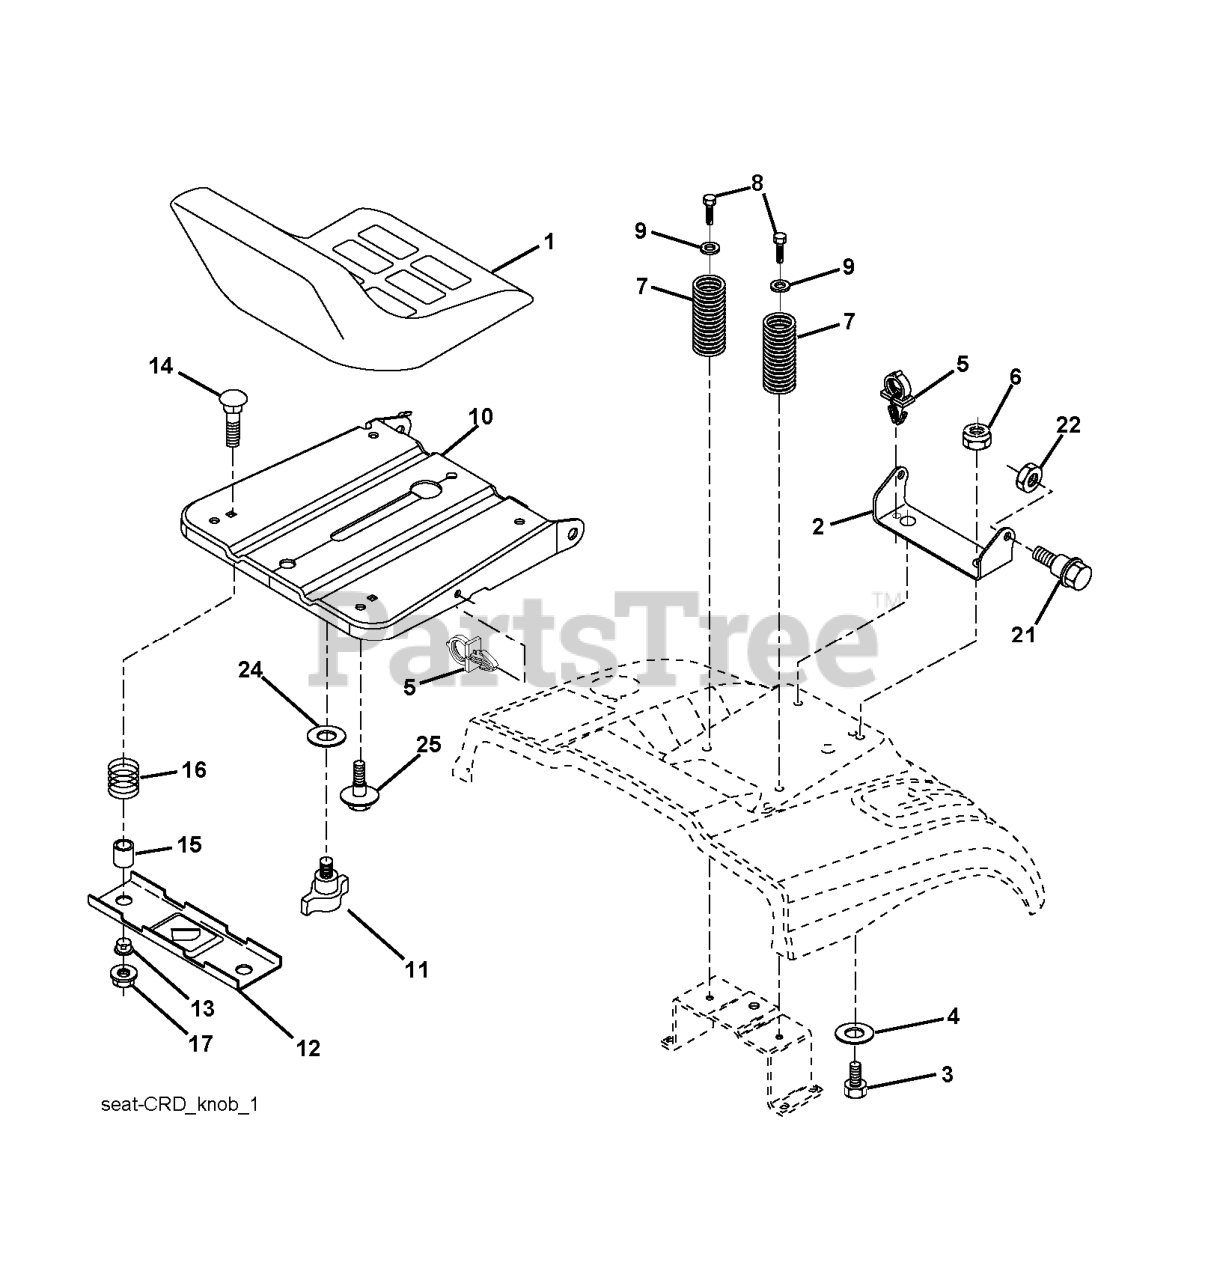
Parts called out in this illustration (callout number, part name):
1	RP SEAT
2	SEAT PIVOT BRKT
3	BOLT, HEX 3/8-16X1
6	NUT
7	SPRING COMPRESSION
8	SCREW 3/8-16X1
9	WASHER
10	PAN.ASM.SEAT.1SLOT
11	KNOB.SEAT.ADJ.WINGNUT
12	BRKT.MNTNG.SWITCH.SEAT.BLACK
14	BOLT.ROUND.HEAD.SQUARE.NECK
15	SPACER SPLIT 28X.96
17	NUT T
21	BOLT.SHOULDER.5/16-18
22	NUT.71038.31-18.HEX.NYLOCK
25	BOLT,SHOULD
